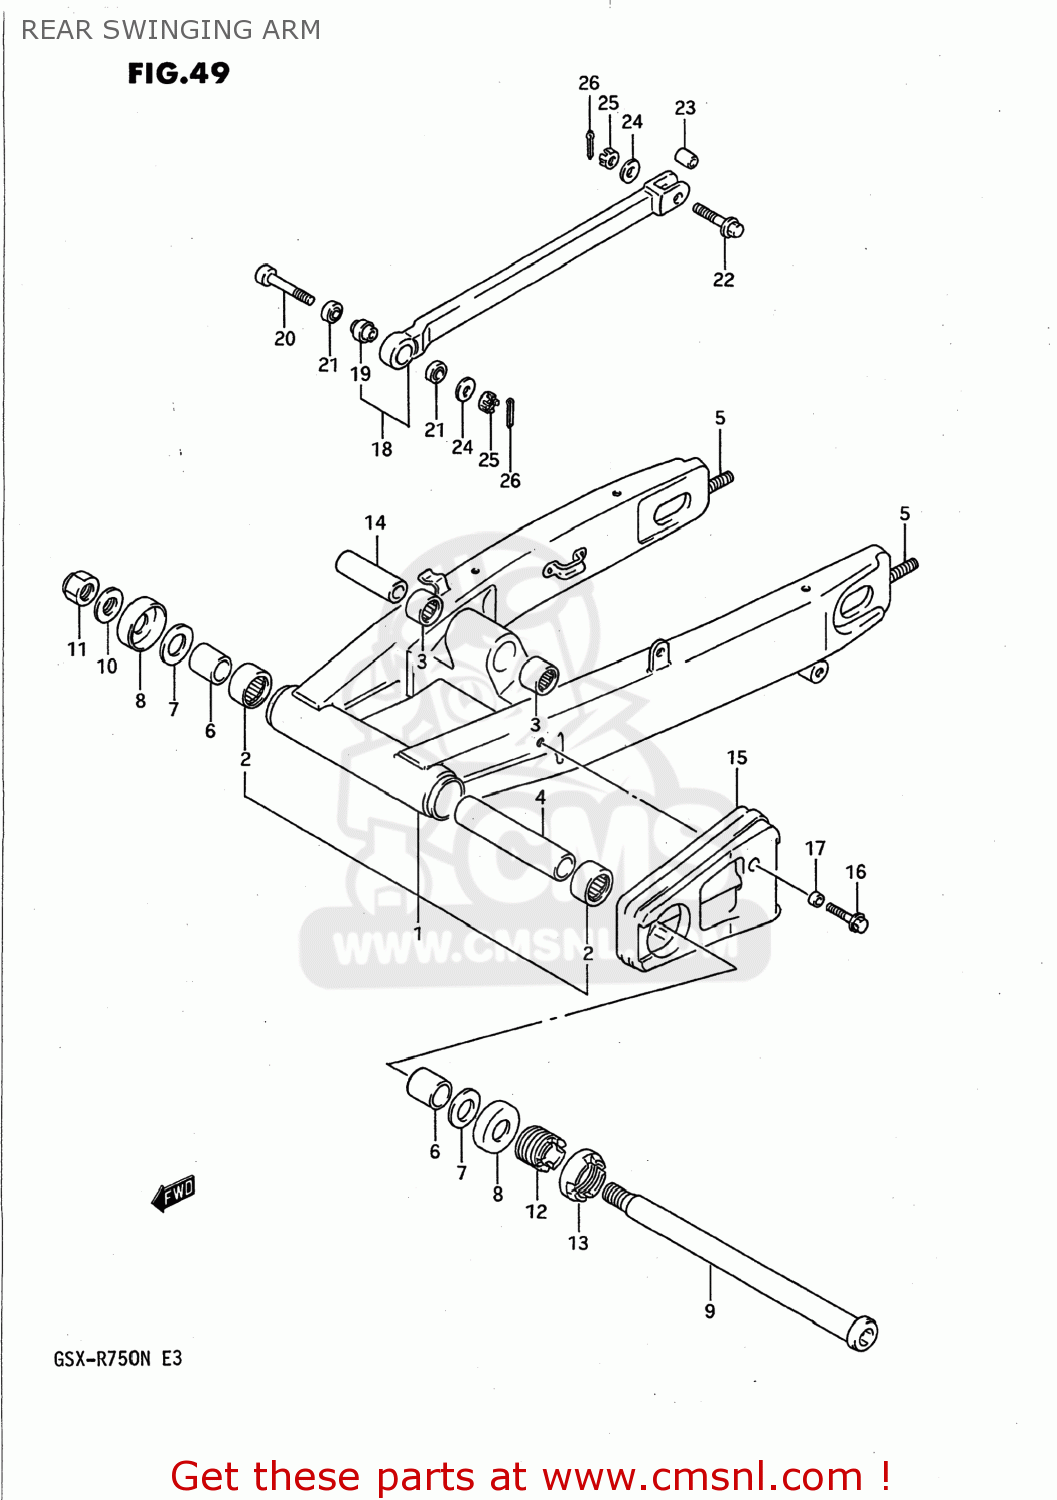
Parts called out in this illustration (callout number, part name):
1	SWING ARM ASSEMBLY,REAR
2	BEARING(25X33X30)
3	BEARING(20X27X23.5)
4	SPACER,RR SWGARM PIVOT CTR
5	STUD,CHAIN ADJUSTER BOLT
6	SPACER,RR SWGARM PIVOT BERRING
7	WASHER
8	DUST SEAL,RR SWGARM PIVOT
9	SHAFT,REAR SWING ARM PIVOT
10	WASHER
11	NUT
12	BOLT,RR SWGARM PIVOT
13	NUT,REAR SWING ARM PIVOT
14	SPACER,RR CUSHION LEVER
15	BUFFER,CHAIN TOUCH DEFENSE
16	BOLT 6X20,WITH PLAIN WASHER
17	SPACER
18	TORQUE LINK SET,REAR
19	SPHERICAL BEARING,TORQUE
20	BOLT(8X48)
21	22
22	BOLT(8X38)
23	SPACER,RR TORQUE LINK RR
24	WASHER
25	NUT 8MM
26	PIN 20X20
